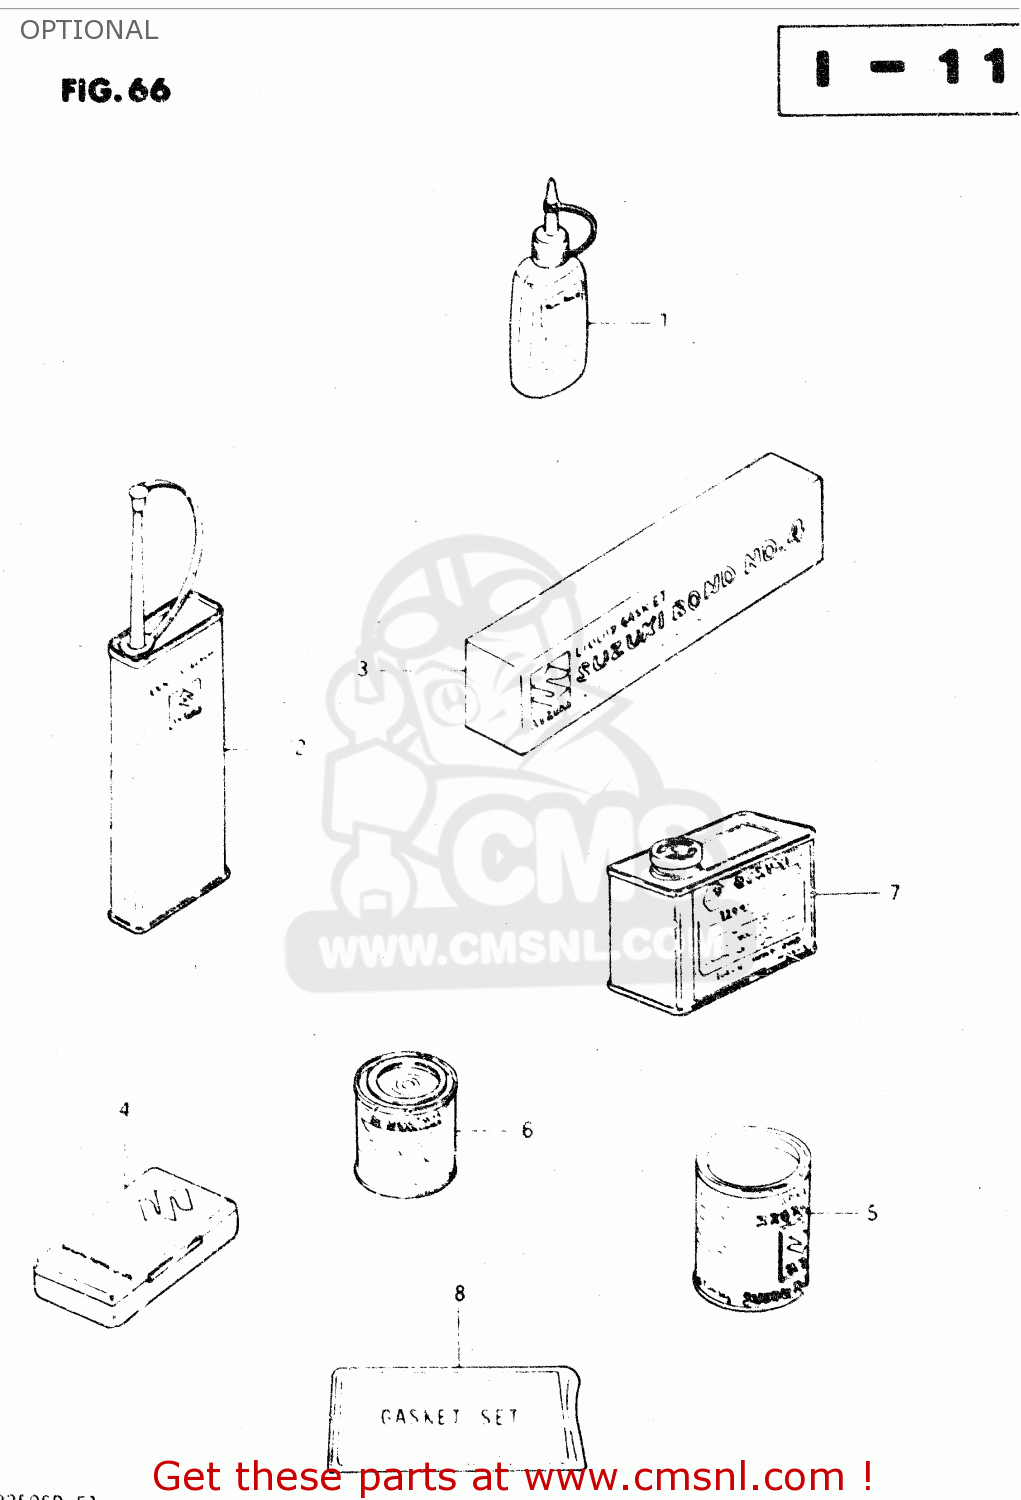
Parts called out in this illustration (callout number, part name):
1	THREAD LOCK NO
2	THREAD LOCK NO.1401 CLEAR 200G
3	BOND 1104
4	TUBE REPARING TOOL
5	GREASE(C)EP2 LITHIUM 150G
6	PAINT,BLACK
7	PAINT (BLACK)
8	GASKET SET (MCA)
